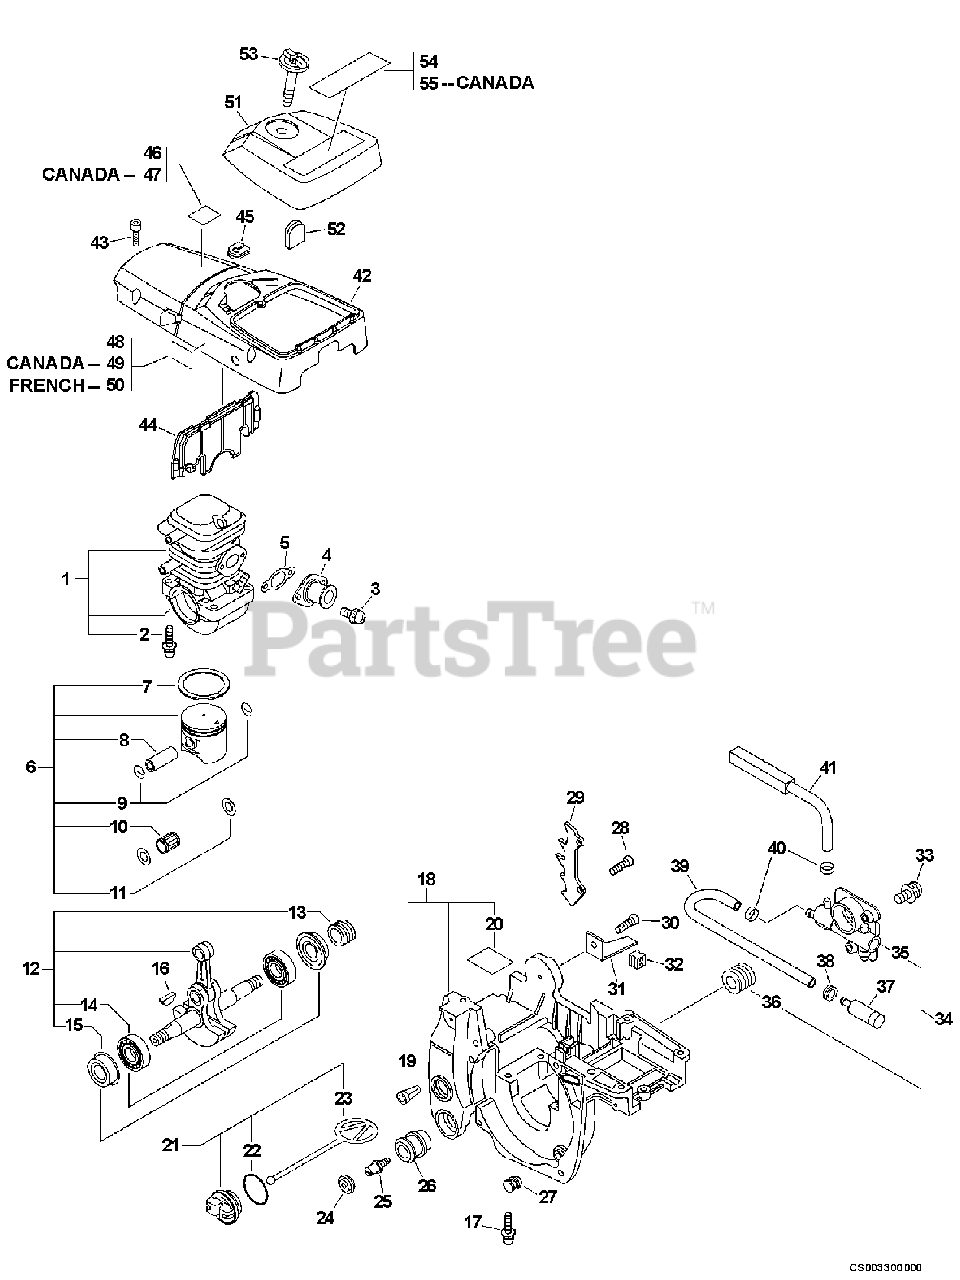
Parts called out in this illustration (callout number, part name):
1	CRANKCASE SET
2	SCREW - 5X22
3	SCREW - 5X14
4	ADAPTOR, INTAKE
5	GASKET, INTAKE
6	PISTON KIT
7	RING, PISTON
8	PIN, PISTON
9	RING, RETAINING
10	BEARING, NEEDLE
11	SPACER, PISTON
12	CRANKSHAFT ASSY
13	GEAR - WORM
14	BEARING, BALL - 6201
15	SEAL, OIL - 12
17	SCREW - 5X30
18	ENGINE COVER ASSY
19	VENT, TANK
20	DEFLECTOR, HEAT
21	CAP ASSY - BLACK
22	O-RING - 25
23	CONNECTOR, CAP
24	CAP, CUSHION
27	CUSHION
28	SCREW - 5X20 -- TAPPING
30	SCREW - 5X16
31	CATCHER, CHAIN
33	SCREW - 4X12
34	AUTO-OILER ASSY
35	ADAPTOR, INTAKE
35	AUTO-OILER ASSY
36	SCREW - 5X14
36	GEAR - WORM
37	GASKET, INTAKE
37	FILTER, OIL
39	PIPE - OIL
40	CLIP - 6.5
41	PIPE, OIL OUTLET
42	COVER, ENGINE
43	SCREW - 5X20
44	PLATE, INSULATOR
45	GROMMET
46	LABEL - BAR & CHAIN
47	LABEL - BAR & CHAIN
48	LABEL - KICK BACK
49	LABEL - KICK BACK
50	LABEL - KICK BACK
51	AIR FILTER COVER ASSY - BLACK
53	THUMBSCREW
54	LABEL - MODEL CS-370
55	LABEL - MODEL CS-370
